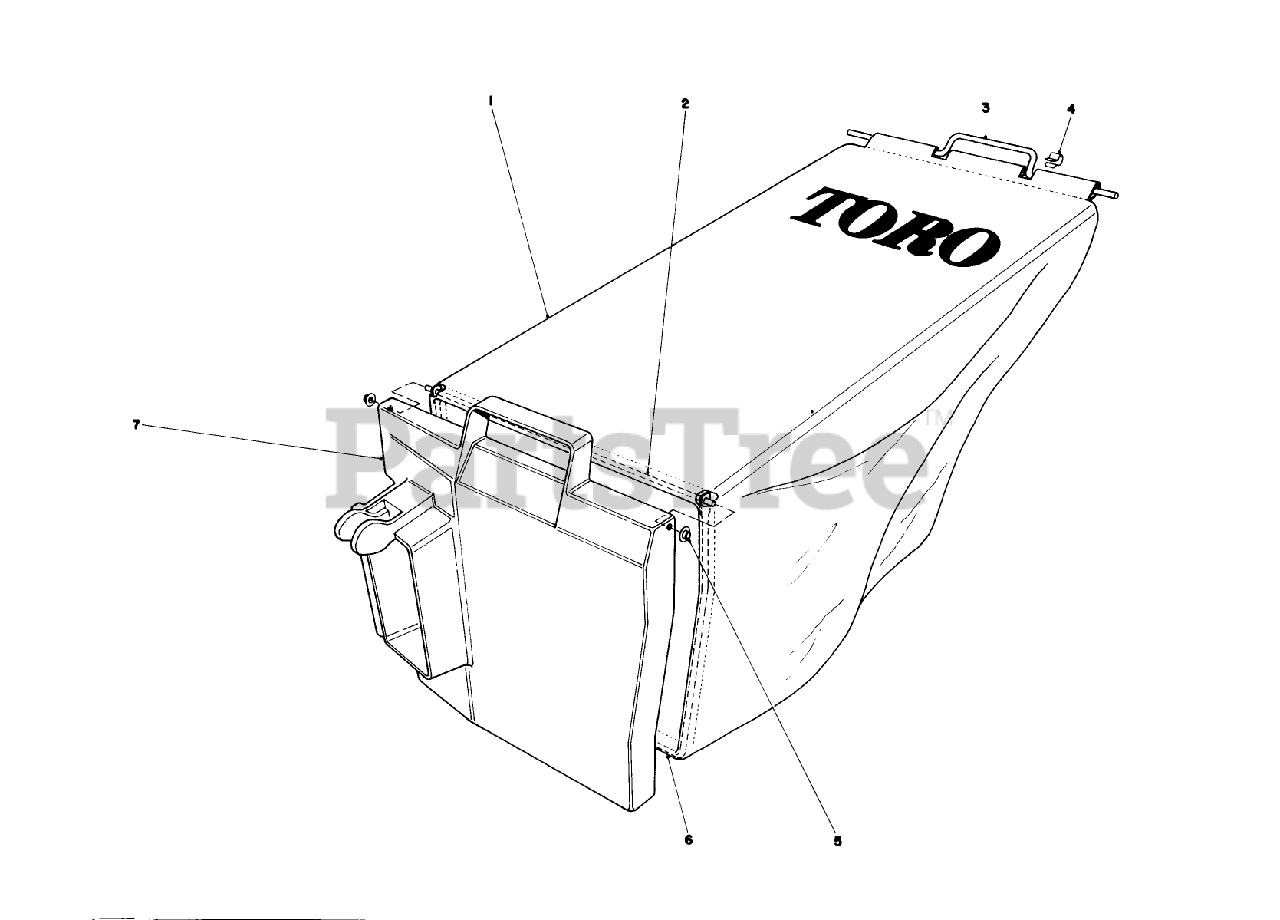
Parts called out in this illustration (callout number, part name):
1	18 BAGGER BAG 33-4552
2	HINGE
3	Handle Bag
5	NUT-PUSH
6	Frame Bag
7	Door-Bag
